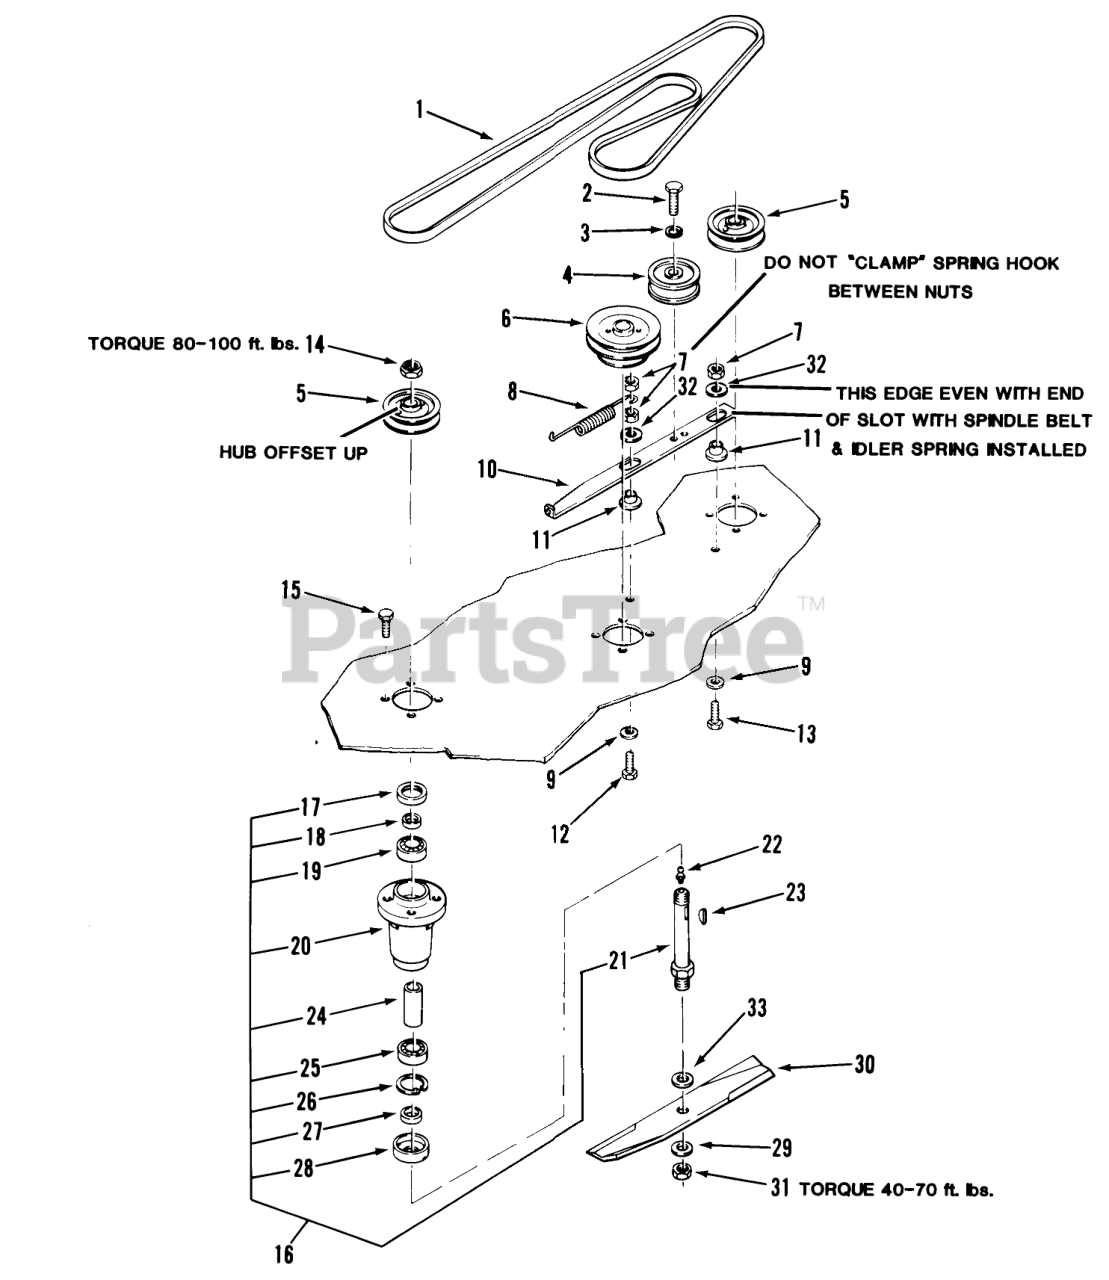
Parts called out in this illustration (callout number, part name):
1	V-BELT
1	V BELT
2	BOLT HEX SPECIAL
2	Bolt
3	LOCKWASHER
4	Idler Pulley
5	PULLEY-BLADE DRIVE
6	PULLEY-48 MOWER SPDL
6	PULLEY-42 MOWER SPDL
7	NUT
8	SPRING-EXTENSION
9	WASHER
10	BAR-IDLER SUPPORT
11	SPACER-BUSHING
12	Bolt
13	Bolt
14	Nut
15	Bolt
16	Spindle Assembly
18	SPACER-SEAL
19	BEARING-BALL
20	HOUSING-SPINDLE
21	7" X 3/4" SHAFT.JAK
22	Zerk
23	Hi-Pro Key 3/16 x 5/8
24	SPACER
25	BEARING-BALL
26	Ring-Snap
27	SPACER-BLADE
28	CUP-SPINDLE
29	SpeciaI Washer
30	BLADE KIT (3 PACK)
30	14IN BLADE KIT
30	BLADE KIT
31	Nut
32	WASHER
33	Washer
